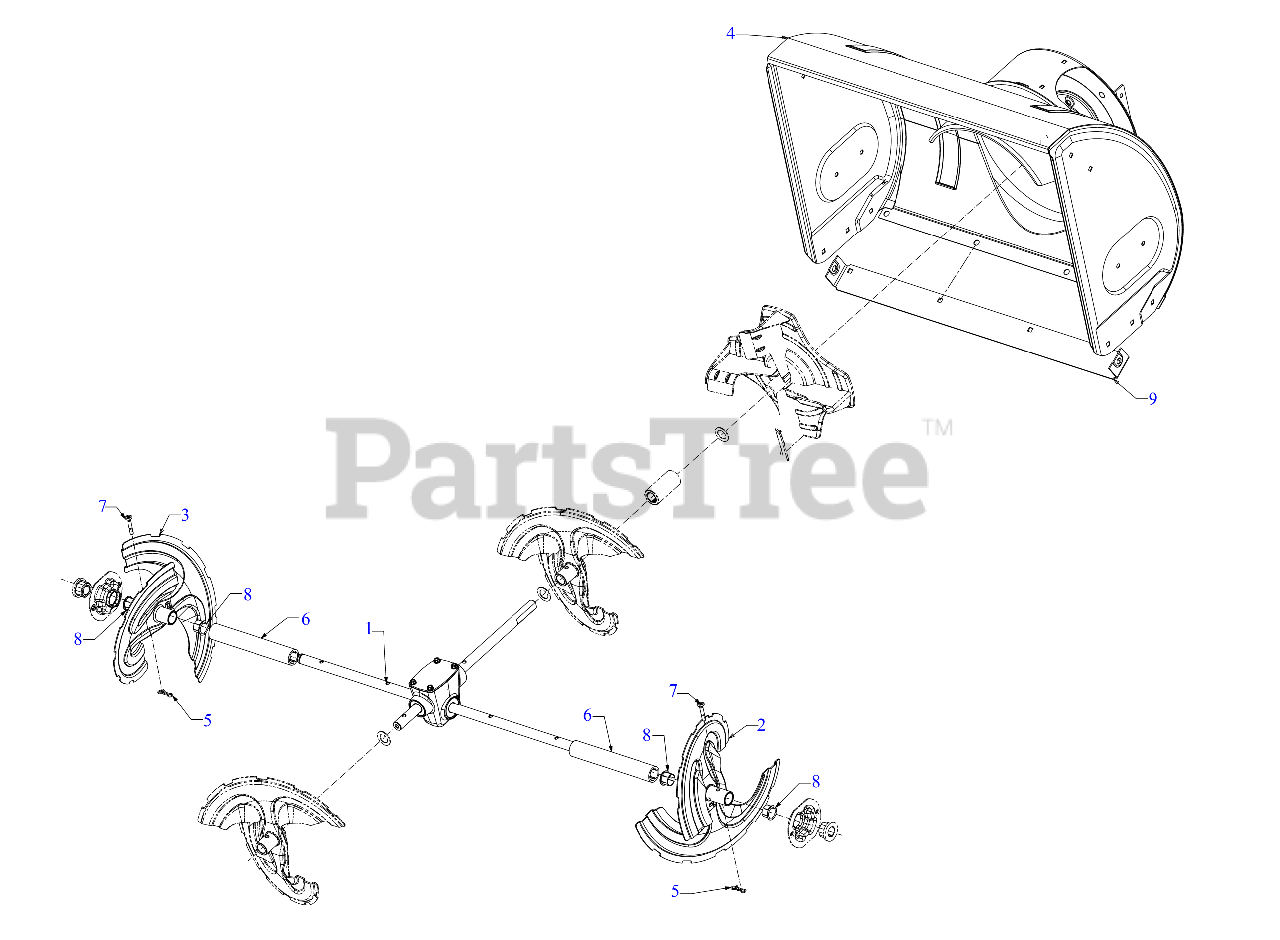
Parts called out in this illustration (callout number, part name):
1	GEARBOX ASSEMBLY 28"
5	BOW TIE COTTER PIN 1/4-5/16
6	SPACER
7	SHEAR PIN (.25 x 1.50)
8	FLANGE BUSHING
